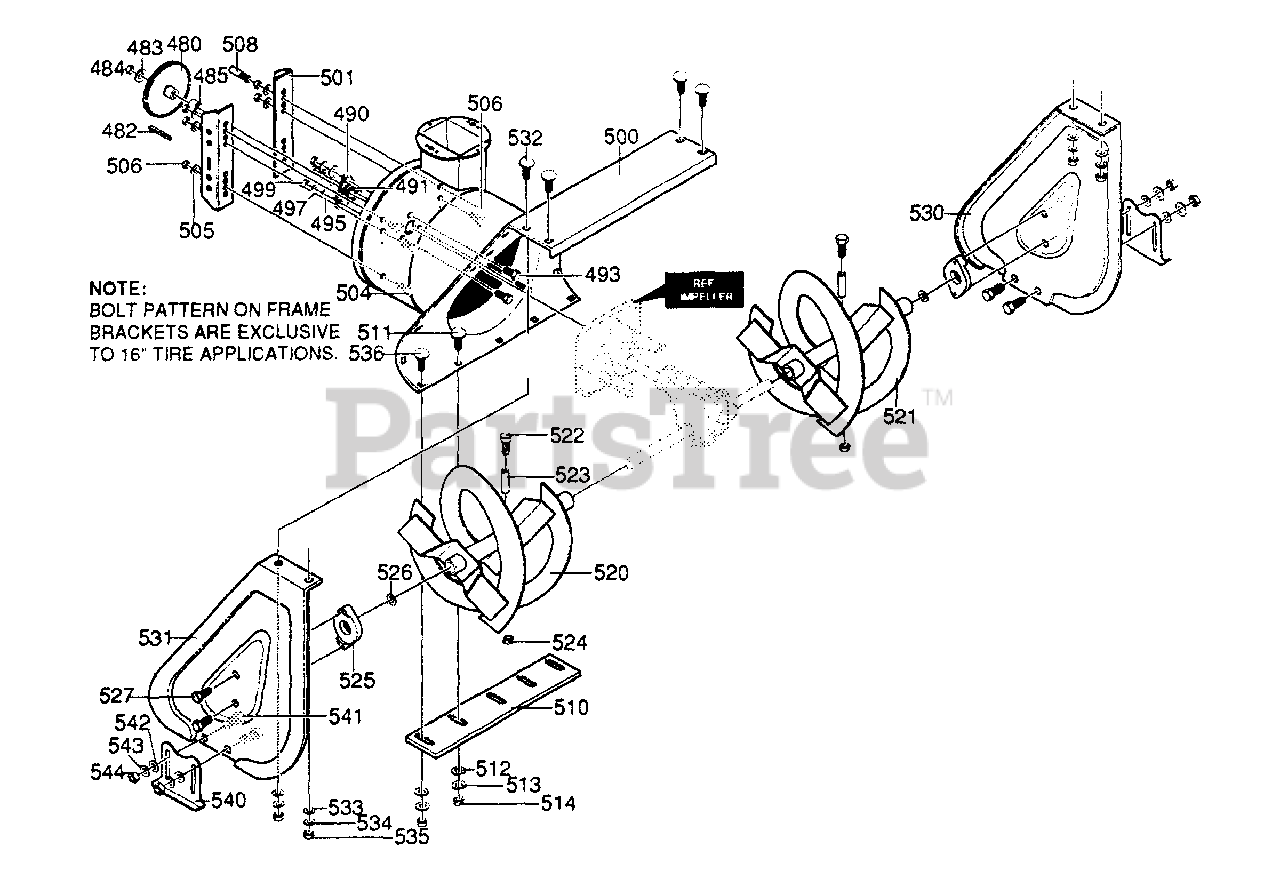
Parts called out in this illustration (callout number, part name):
480	PULLEY, V4L- 8.40 OD
482	KEY, SQUARE.18 SQx.88 LG
483	FLATWASHER,.53x1.00x.063
484	NUT, 1 /2-20 REGHXCTRLK
485	SPACER, SLEV.676x1.00x.53
490	RETAINER, BALL BRNG
491	BRNG, BALL 6203-2AA-C3
493	SCREW, 5/16-18x.75 HHC
495	FLATWASHER, .344x.69x.065
497	WASHER, HVSPTLK.328x.60x.09
499	NUT, 5/16-18 REGHEX
500	HOUSING, ASSY
501	BRACKET & NUTS ASSY
504	SCREW 3/8-16x.75
505	WASHER .393x.68x.10
506	NUT, 3/8-16 REGHEXCTRLK
508	HUB, BRAKE ARM
510	BLADE, SCRAPER, MF 27"
511	BOLT, 5/16-18x.75 CARRLN
512	FLATWASHER, .344x.69x.065
513	WASHER, HVSPTLK.328x.60x.09
514	NUT, 5/16-18 REGHEX
520	AUGER, ASSY MF LH 25"
521	AUGER, ASSY MF RH 25"
522	SCREW, 1/4-20x1.75 HHCFT
523	SPACER, SLEV.250x.47x.20
524	NUT, 1/4-20 REGHEXCTRLK
525	AUGER SHAFT BEARING
526	FLATWASHER, 1.005x1.31x.035
527	SCREW, 5/16-18x.75 WAHHTAP
530	PLATE, AUGER HSNG END, LH
531	PLATE, AUGER HSNG END, RH
532	BOLT, 5/16-18x.75 CARRLN
533	FLATWASHER, .344x.69x.065
534	WASHER, HVSPTLK.328x.60x.09
535	NUT, 5/16-18 REGHEX
536	BOLT, 5/16-18x1.00 CARRLN
540	SKID, HEIGHT ADJUST
541	BOLT, 5/16-18x.75 CARRLN
542	FLATWASHER, .344x.69x.065
543	WASHER, HVSPTLK.328x.60x.09
544	NUT, 5/16-18 REGHEX
